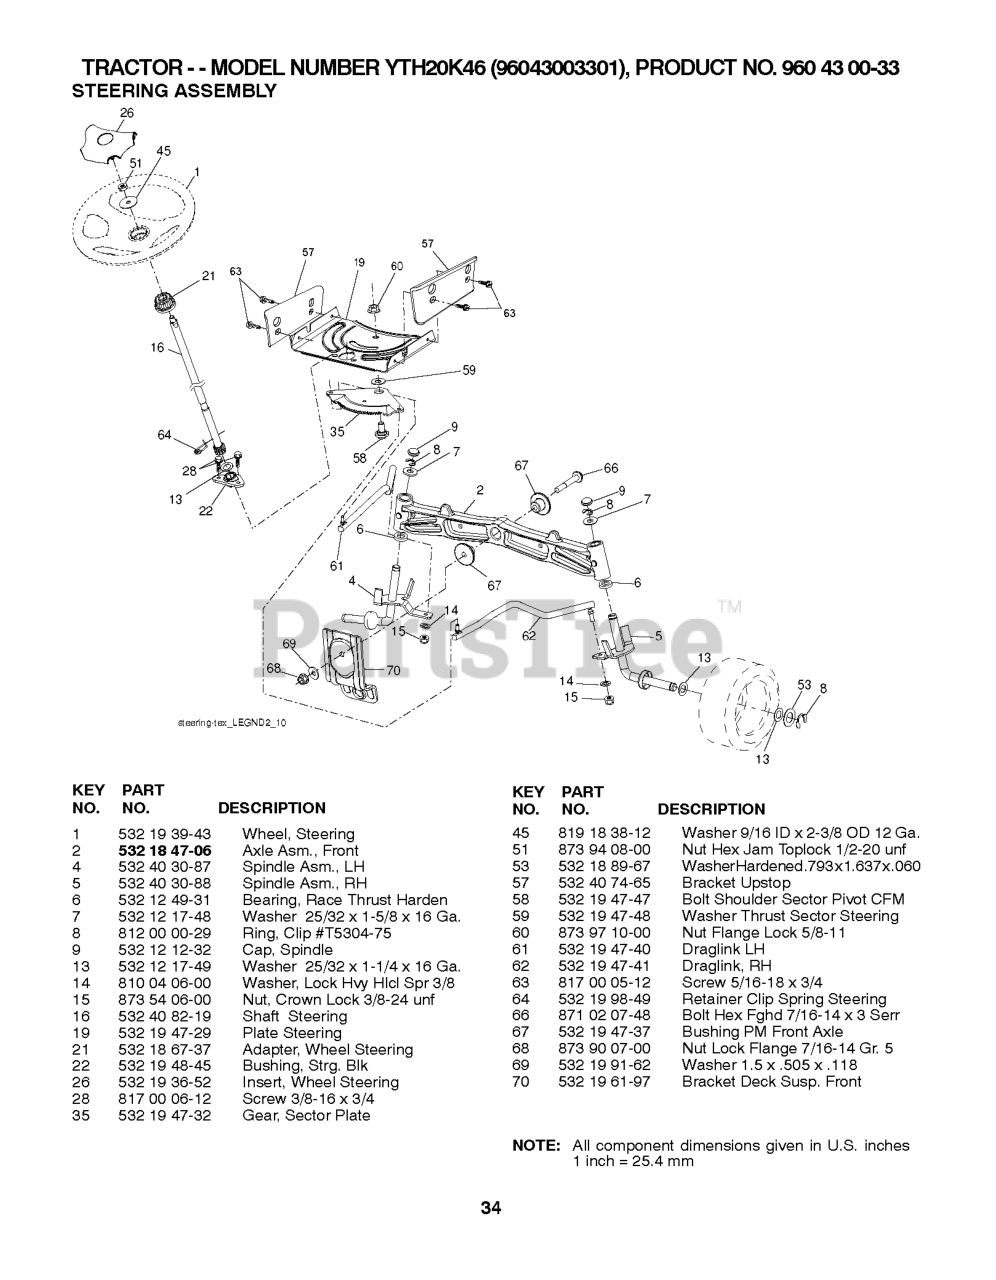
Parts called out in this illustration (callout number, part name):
1	WHEEL.STEERING.LEGEND2.GRY
2	AXLE ASSY FRONT
4	SPINDLE.WELDED.LH.15"TEX
5	SPINDLE.WELDED.RH.15"T
6	THRUST WASHER
9	CAP.SPINDLE.BLACK
14	WASHER, LOCK 3/8
15	NUT CROWNLOCK 3/8-24
16	SHAFT, STEERING
19	PLATE.STEER.DDL.NLT/NG
21	ADAPTER, WHEEL STNG..
22	BUSHING.ASM.STEERING.A
26	INSERT.CAP.STRG.WH.GRAY
28	SCREW, 3/8-16X3/4
35	GEAR.SECTOR.PLATE.DDL.
45	WASHER 9/16"ID, 2 3/8"OD
51	NUT.HEX.1/2-20
53	WASHER.HARDENED
57	BRACKET.UPSTOP.TEX
58	BOLT.SHOULDER.SECTOR.P
59	WASHER.THURST.SECTOR.S
60	NUT FLANGE LOCK 5/8-11
61	DRAGLINK.LH.BALLSTUD.D
62	DRAGLINK.RH.BALLSTUD.D
63	SCREW
64	RETAINER.CLIP.SPRING.S
66	BOLT HEX FGHD 7/16-14 X 3 SERR
67	BUSHING.PM.FRONT AXLE
68	NUT.LOCK.FLANGE.7/16
69	WASHER.1.5X.505X.118
70	BRKT.DECK.SUSPENSION.F
